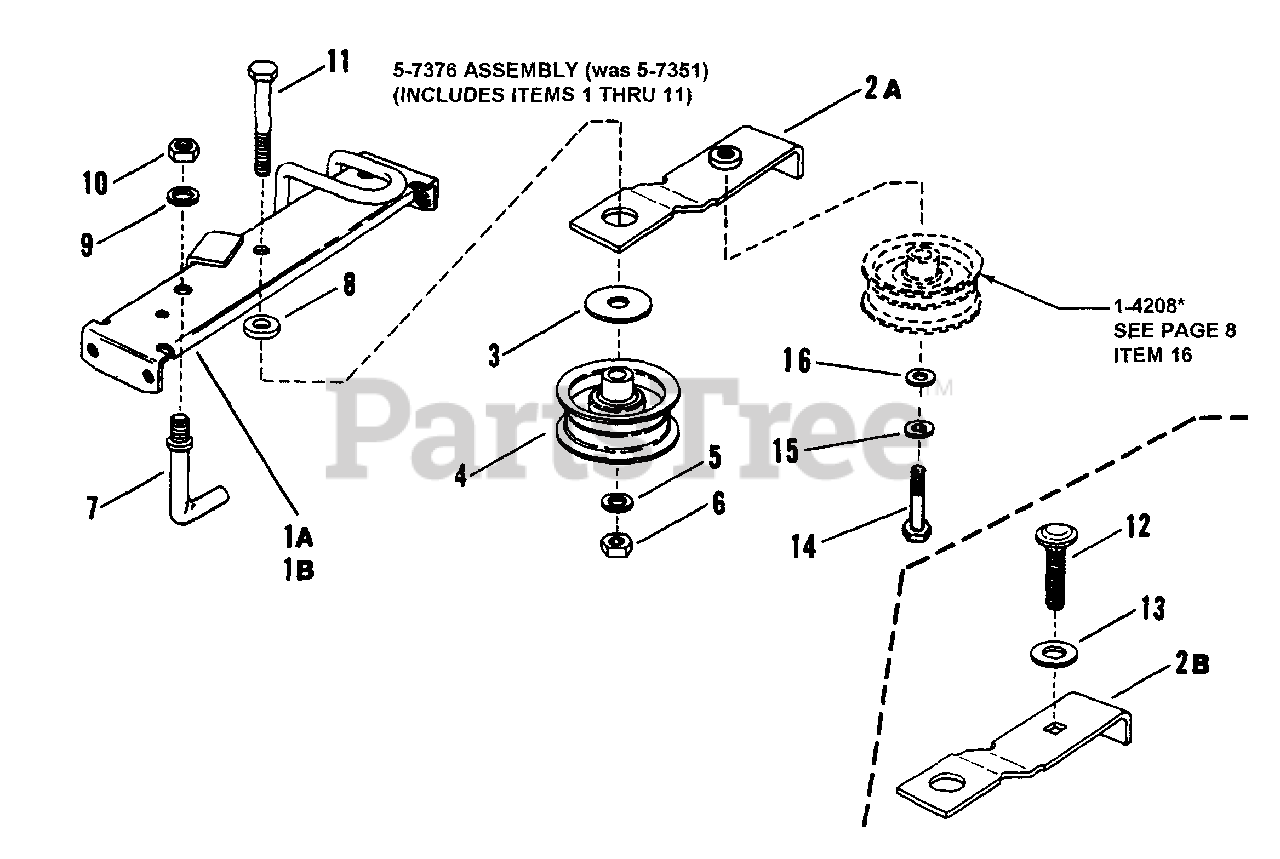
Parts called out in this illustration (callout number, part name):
1A	BRACKET, Idler
1B	BRACKET, Idler
2A	ARM, Idler
2B	ARM, Idler
3	WASHER, 11/32" Flat
4	IDLER
5	WASHER, 5/16 Split Lock
6	NUT, 5/16-24 Hex
7	GUIDE, Belt
8	SPACER, .328" ID, .625" OD, .21" Thick
9	WASHER, 3/8" Split Lock
10	NUT, 3/8-24 Hex, Grade 2
11	SCREW, 5/16-24 x 2" Hex Head Cap, Grade 2
12	BOLT, 3/8-16 x 1-1/2" Short Neck Carriage, Grade 2
13	WASHER, 1/2" Shim
14	SCREW, 3/8-16 x 1-1/2" Hex Head Cap, Grade 5
15	WASHER, 3/8" Split Lock
16	WASHER, 3/8" SAE Flat
